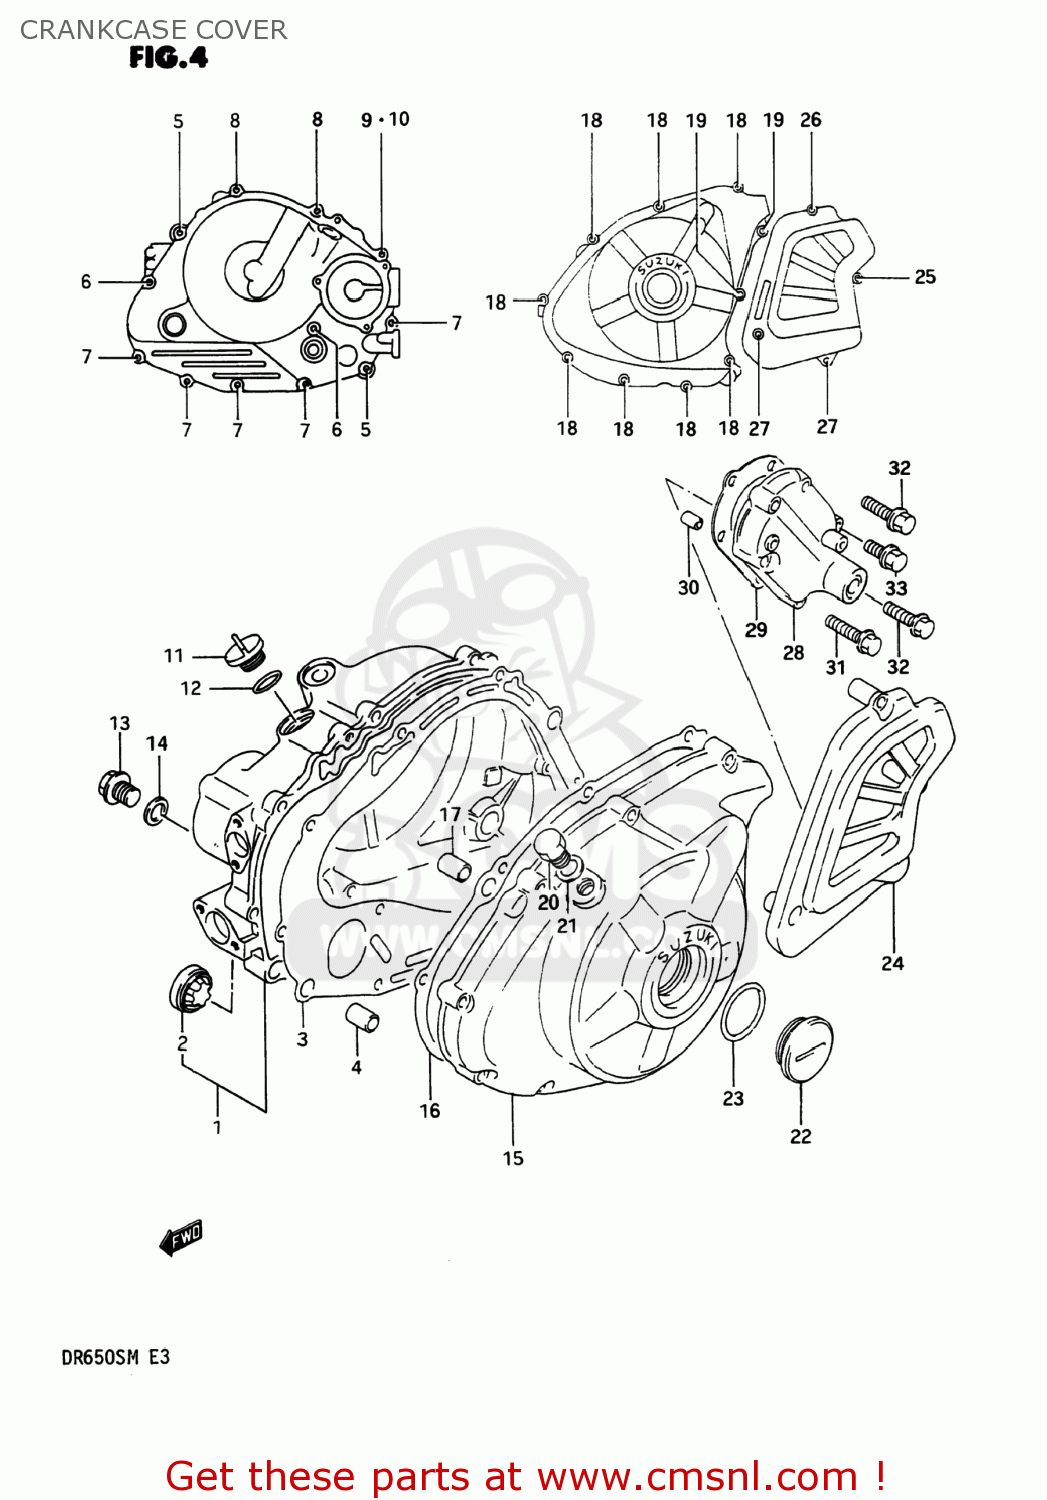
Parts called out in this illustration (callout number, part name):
1	COVER,CLUTCH
2	LENS,OIL LEVEL CHECK
3	GASKET,CLUTCH COVER
4	PIN
5	BOLT 6X50
6	BOLT 6X40
7	BOLT 6X35
8	BOLT 6X25
9	BOLT 6X25
10	WASHER
11	PLUG
12	O RING(D:3.1,ID:16.8)
13	PLUG(14X12)
14	GASKET(14X19.2X2) (NAS)
15	COVER,GENERATOR
16	GASKET,MAGNETO COVER (MCA)
17	PIN
18	BOLT 6X30
19	BOLT 6X25
20	PLUG(12X9)
21	GASKET(12.1X16.2X3.7) (NAS)
22	PLUG
23	O RING(D:3.1,ID:32.7)
24	COVER,ENGINE SPROCKET
25	BOLT
26	BOLT 6X35
27	BOLT 6X20
28	COVER,GEAR SHIFT
29	GASKET,GEAR SHIFT COVER (MCA)
30	PIN
31	BOLT 6X35
32	BOLT 6X30
33	BOLT 6X20
